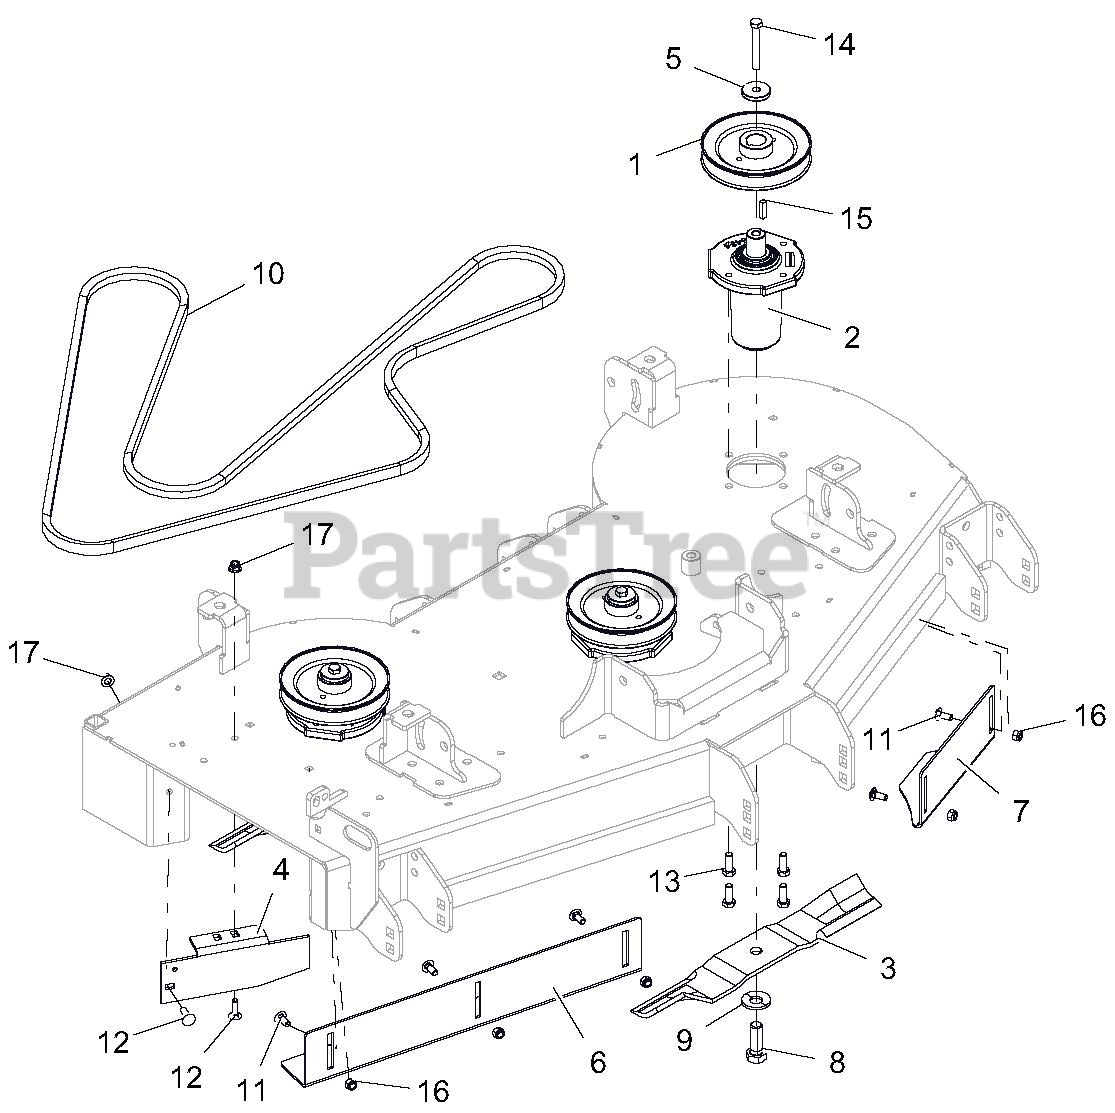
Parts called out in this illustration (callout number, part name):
1	PULLEY, V-1.00 ID X 5.75 OD
2	SERVICE, ASM SPINDLE- DUCTILE
3	BLADE, 16.19" MOWER
4	BAFFLE, 44-48" SIDE DISCHARGE
5	RETAINER, SHEAVE SPINDLE
6	BAFFLE, 48" RH VACUUM
7	BAFFLE, 44/48" LH VACUUM
8	BLT, HEX .62-18X1.75 GR8 YWZC
9	WSHR, BLVL .63X1.625X.14
10	V-BELT, B SECTION RAW EDGE
11	BLT-RDHDSQNK .31-18X.75 G5 YWZC
12	BLT-RDHDSQSHNK .31-18X1.00 G5 Y
13	BLT-HEX .38-16X1.00 GR5 YWZC EP30
14	BLT-HEX .38-16X2.75 GR8 YWZC
15	KEY-SQ .250X.250X1.00 RC 40-50
16	NUT-LK-NYL .312-18 YWZC
17	NUT-LK-NYL-FLG .31-18 YWZC
